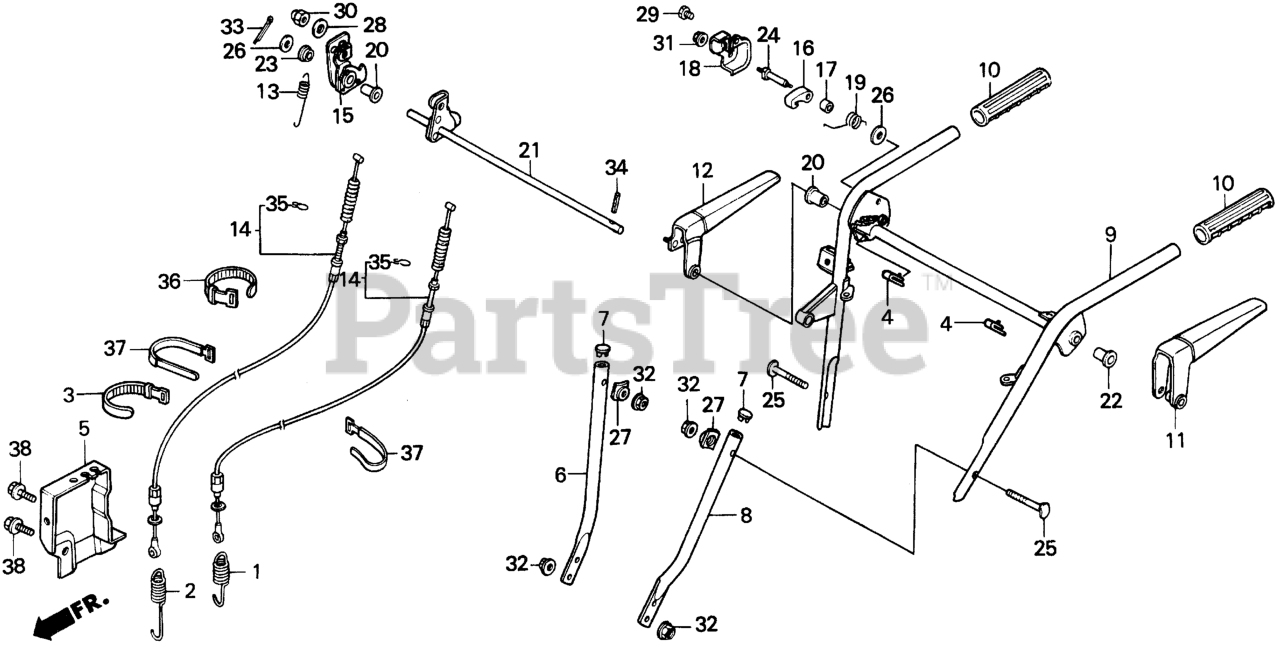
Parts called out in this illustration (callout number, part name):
1	SPRING, TENSION ROLLER
2	SPRING, TENSION ROLLER (NOT AVAILABLE)
5	HOLDER, WIRE
6	HANDLE, R. (LOWER)
7	CAP, HANDLE (LOWER)
8	HANDLE, L. (LOWER)
9	PIPE, HANDLE (UPPER) (NOT AVAILABLE)
10	GRIP, HANDLE
11	LEVER, CLUTCH
12	LEVER, AUGER CLUTCH
13	SPRING, CLUTCH LEVER
14	CABLE, CLUTCH
15	BOSS, CAM LOCK
16	RATCHET, LEVER
17	COLLAR, RATCHET
18	COVER, RATCHET
19	SPRING, RATCHET
20	BUSH (13MM)
21	SHAFT, CLUTCH LEVER (NOT AVAILABLE)
22	BUSH (14MM)
23	BUSH (4.5MM)
24	BOLT, PIVOT (6MM)
25	BOLT, HANDLE HOLDER (8X41)
26	WASHER (10MM)
26	WASHER, THRUST (10MM)
27	WASHER, FRAME JOINT
28	WASHER (6MM)
29	BOLT, HEX. (6X6)
30	NUT, CAP (6MM)
31	NUT, FLANGE (6MM)
32	NUT, FLANGE (8MM)
33	PIN, COTTER (3.0X18)
34	PIN, SPRING (3X16)
36	BAND B1, CABLE
37	BAND B2, CABLE HARNESS
38	BOLT, FLANGE (6X16) Use from Engine SN 2056820.
